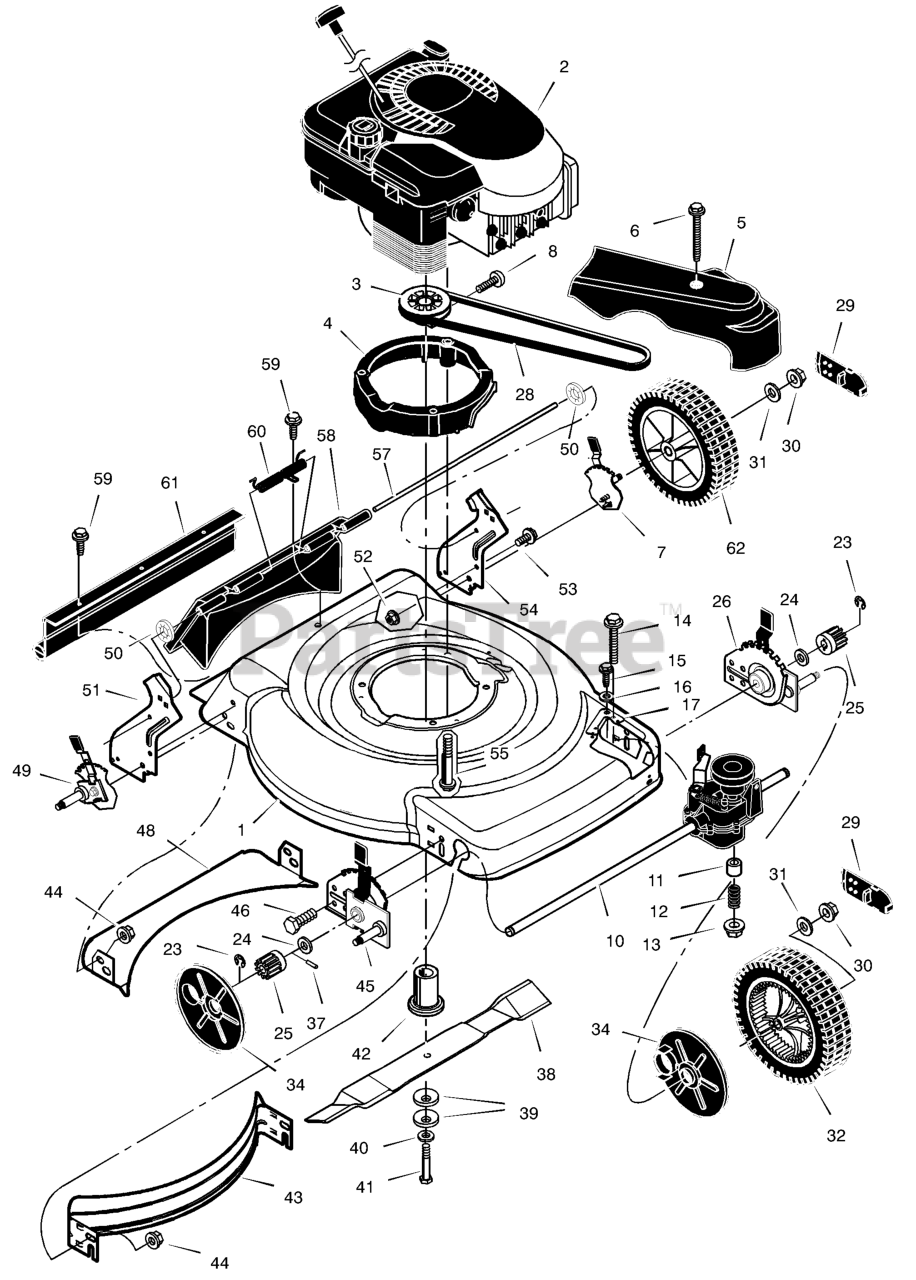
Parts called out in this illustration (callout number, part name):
2	Engine *
3	Pulley, Drive
4	Spacer, Engine
5	Cover, Belt (Black)
7	Adjuster, Left Rear Height
10	Transmission *
12	Spring, Compression
13	Nut
14	Bolt
15	Screw
17	Bracket, Belt Cover
25	Gear, Pinion
26	Adjuster, Left Front Height
29	Cap, Hub
30	Nut, Flange
31	Washer
32	Wheel & Tire, Front
34	Cover, Dust
37	Pin, Drive
39	Washer, Belleville
42	Adapter, Blade
43	Baffle, Front
44	Nut, Flange
45	Adjuster, Right Front Height
46	Bolt
48	Baffle, Rear
49	Adjuster, Right Rear Height
50	Retainer
51	Bracket, Right Handle
52	Nut, Flange
53	Bolt
54	Bracket, Left Handle
55	Bolt, Engine
57	Rod, Pivot
58	Door, Rear (Black)
59	Screw
60	Spring
61	Guard, Rear
62	Wheel & Tire, Rear
